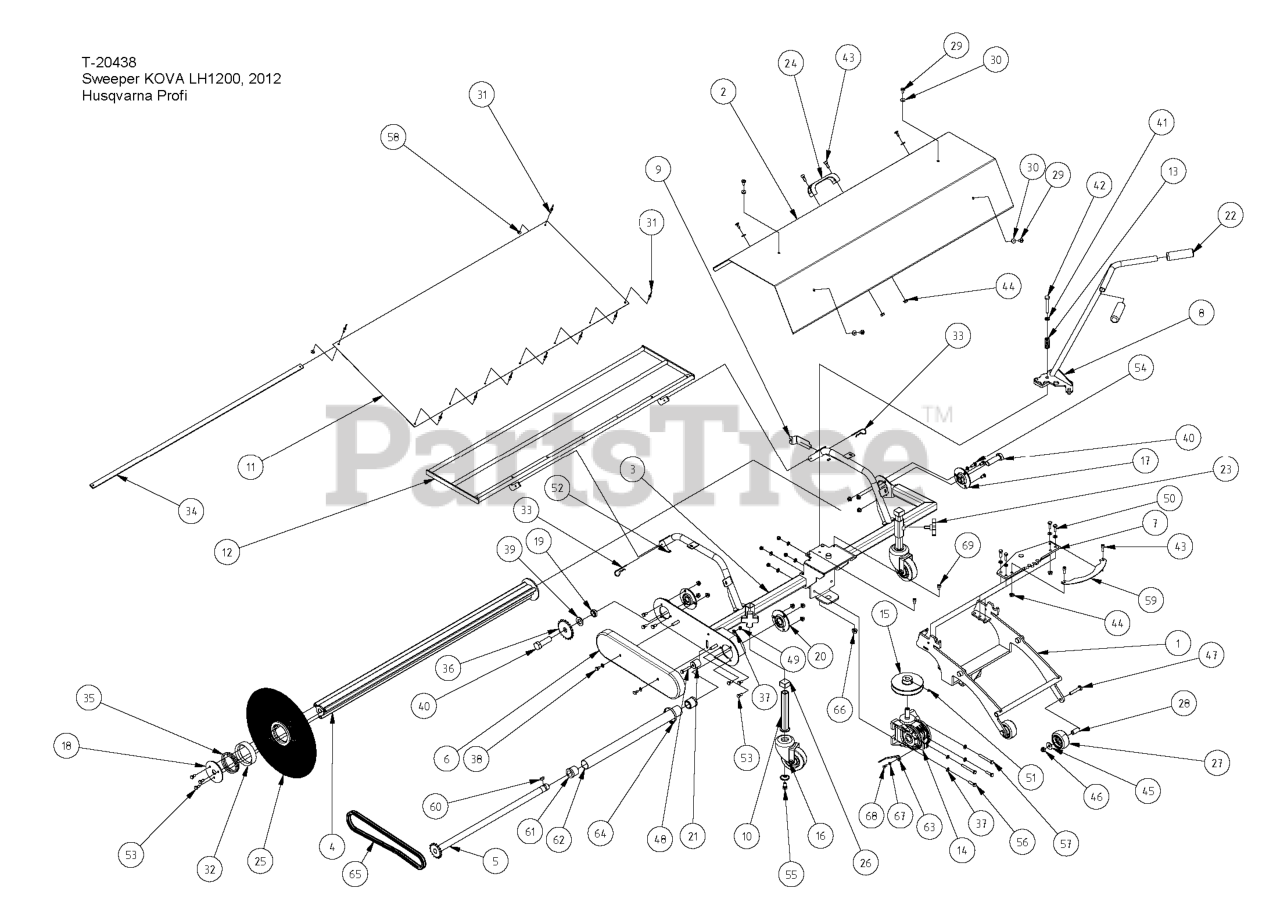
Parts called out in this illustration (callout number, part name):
11	PROTECTION
14	GEAR BOX ASSY
16	SUPPORT WHEEL
21	CHAIN ADJUSTER
27	SUPPORT WHEEL
28	COLLAR
33	COTTER PIN
44	NUT LOCKING
70	DECAL.HUSQVARNA.210MM
